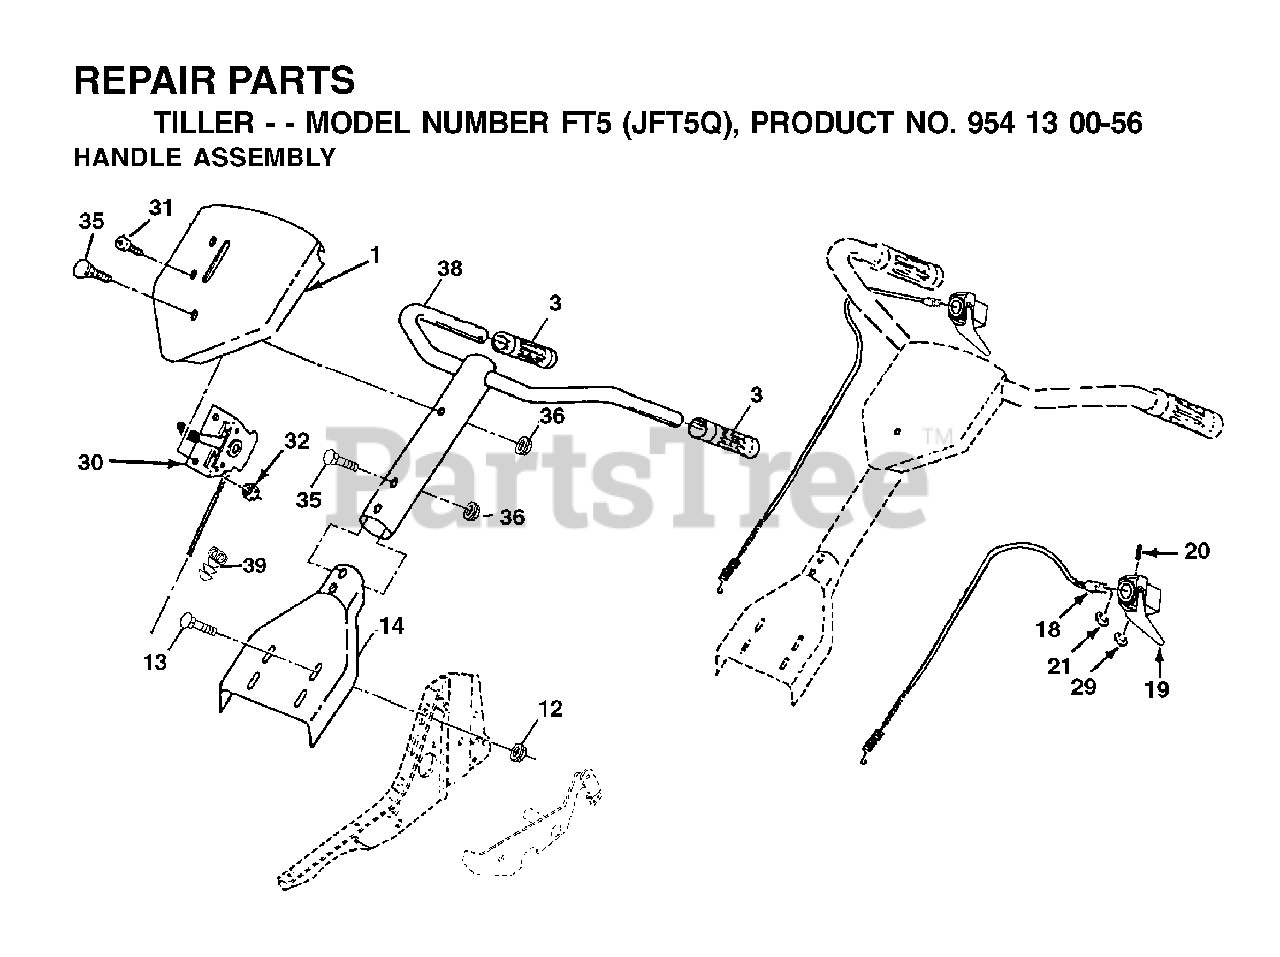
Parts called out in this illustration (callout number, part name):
12	NUT
13	BOLT.RH.SQNK.5/16
14	PANEL ASM. POLE
21	RETAINING RING
29	RETAINING RING
31	SCREW.PNHD.10-24
32	NUT **
35	BOLT.5/16-18X2.5
36	LOCKNUT-FLANGE 5/16-18
39	CLIP.ROUTING DUAL
